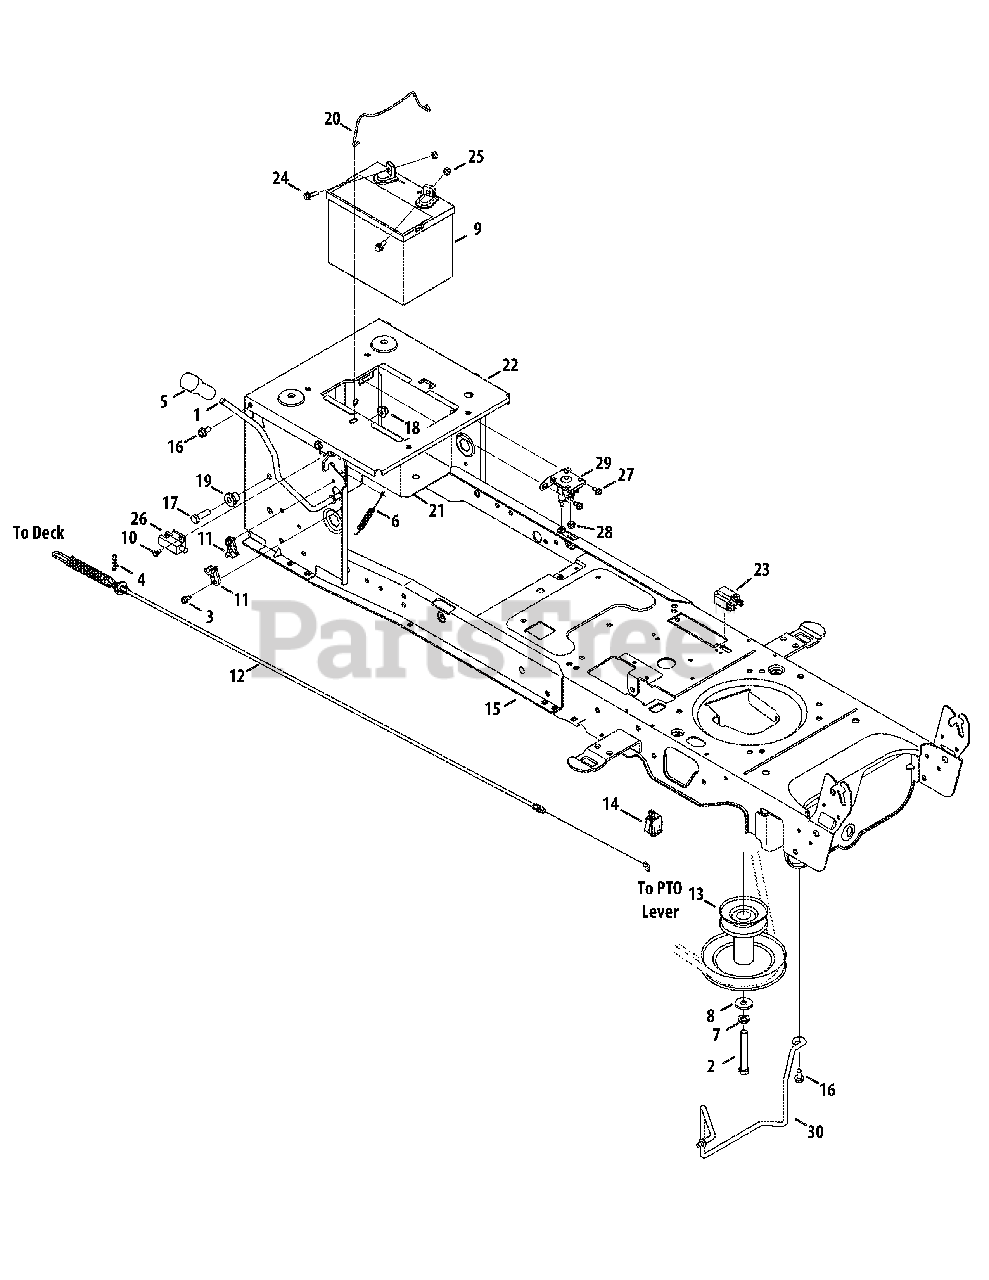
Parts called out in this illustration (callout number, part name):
1	Handle Ass’y, PTO
2	Hex Screw, 7/16-20, 3.50, Gr5
3	Screw, Self-tapping, 1/4-20, 0.50
4	Pin, Cotter, Bow-Tie 72
5	Grip, Handle, 3/8
6	Spring, Ext, .38 Dia x 5.6
7	Washer, Lock, 7/16, Regular Duty
8	Washer, Flat, .450 x 1.250 x .164
9	Battery
10	Screw, Shoulder, #10-32, .500
11	Bearing, PTO
12	Cable, Engag, Deck
13	Pulley, Engine, 3.39 x 6.12 Dia.
14	Switch, Plunger, Snap Mount
15	Frame Ass’y, Lower
16	Screw, Self-tapping, 5/16-18, .750,
17	Hex Screw, 3/8-16, 1.25, Gr5, Std
18	Nut, Flange Lock, 3/8-16, Grf,
19	Spacer, Shoulder, .38 x 1.0 x .70
20	Rod, Battery
21	Tray, Battery
22	Bracket, Frame, Seat
23	Switch, 3-Pole
24	Hex Flange Screw, 1/4-20, .75, Gr5
25	Nut, Sems, 1/4-20
26	Switch, Interlock
27	Screw, Self-tapping, 1/4-20, 0.375,
28	Nut, Flange Lock, 1/4-20, Grf,
29	Solenoid, 12V, 100 Amp, 4 term
30	Rod, Keeper
